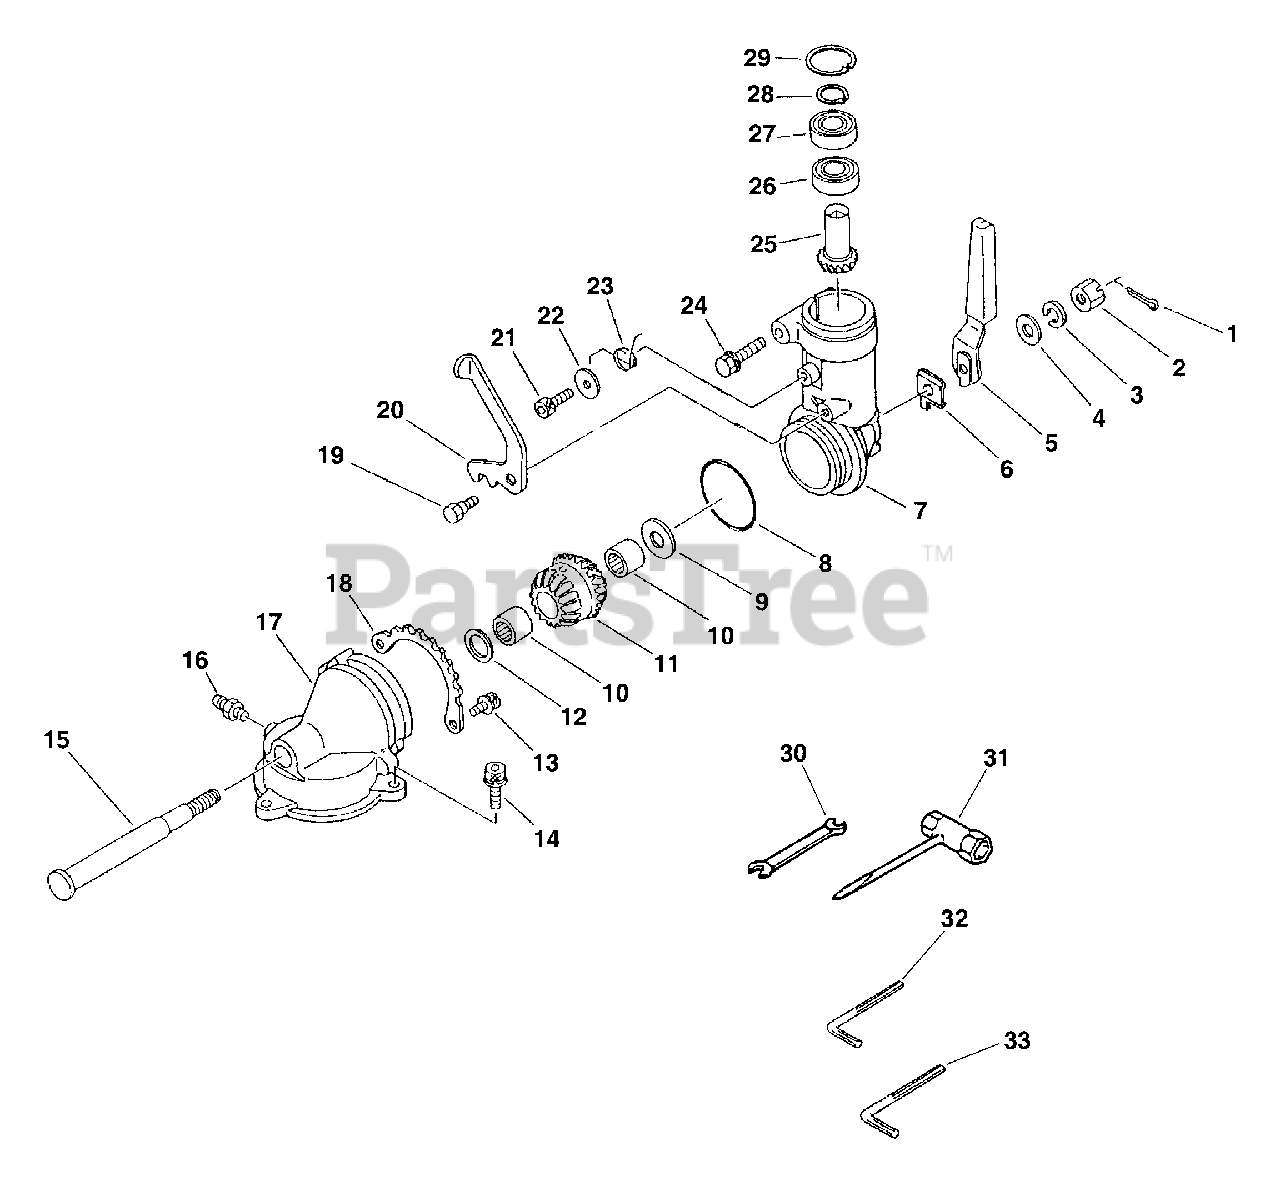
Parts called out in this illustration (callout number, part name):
1	PIN, COTTER 1.6×16
2	NUT, SLOT 6
3	WASHER, SPRING 6
5	PIECE, LEVER
6	PLATE, ANGLE
7	CASE, GEAR
8	O-RING 32
10	BEARING, NEEDLE
11	GEAR, BEVEL
12	WASHER
13	BOLT 4×10
14	BOLT 5×18
15	SHAFT, GEAR
16	FITTING, GREASE
17	COVER, GEAR CASE
18	RESETTER, LATCH
20	PAWL
21	BOLT 5×14
22	WASHER 5.5×12×0.8
23	SPRING, THROTTLE LOCKOUT
24	BOLT 5×35
25	GEAR, DRIVE
26	BEARING, BALL 6900
27	BEARING, BALL 6900Z
28	RING, SNAP Ø10
29	RING, SNAP Ø22
30	SPANNER 8×10
31	T-WRENCH 17x-19 L200
32	WRENCH, ALLEN 3 MM
33	WRENCH, ALLEN 4 MM
